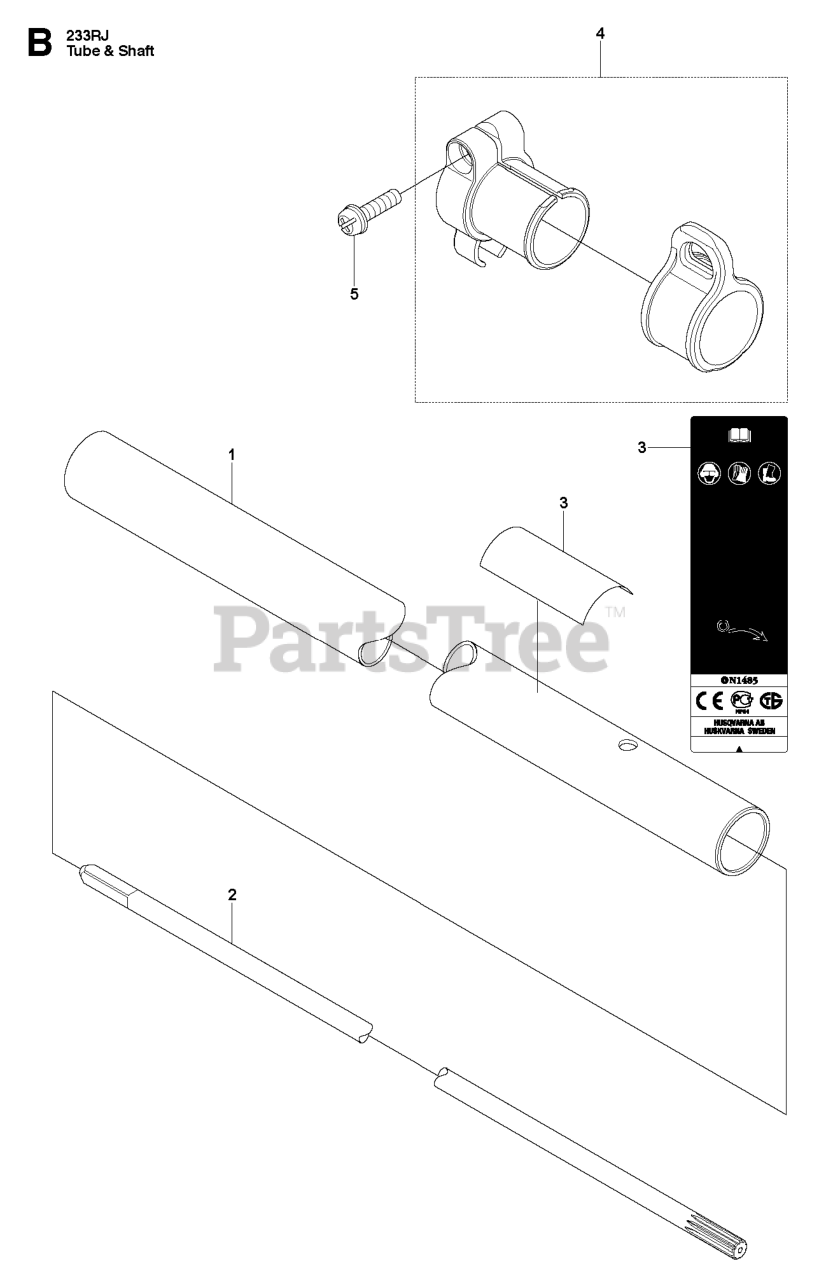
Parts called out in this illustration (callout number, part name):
1	PIPE ASSY
2	SHAFT
3	DECAL
4	HANGER COMP.
5	SCREW, M5x20 (RPLS 140075510)
